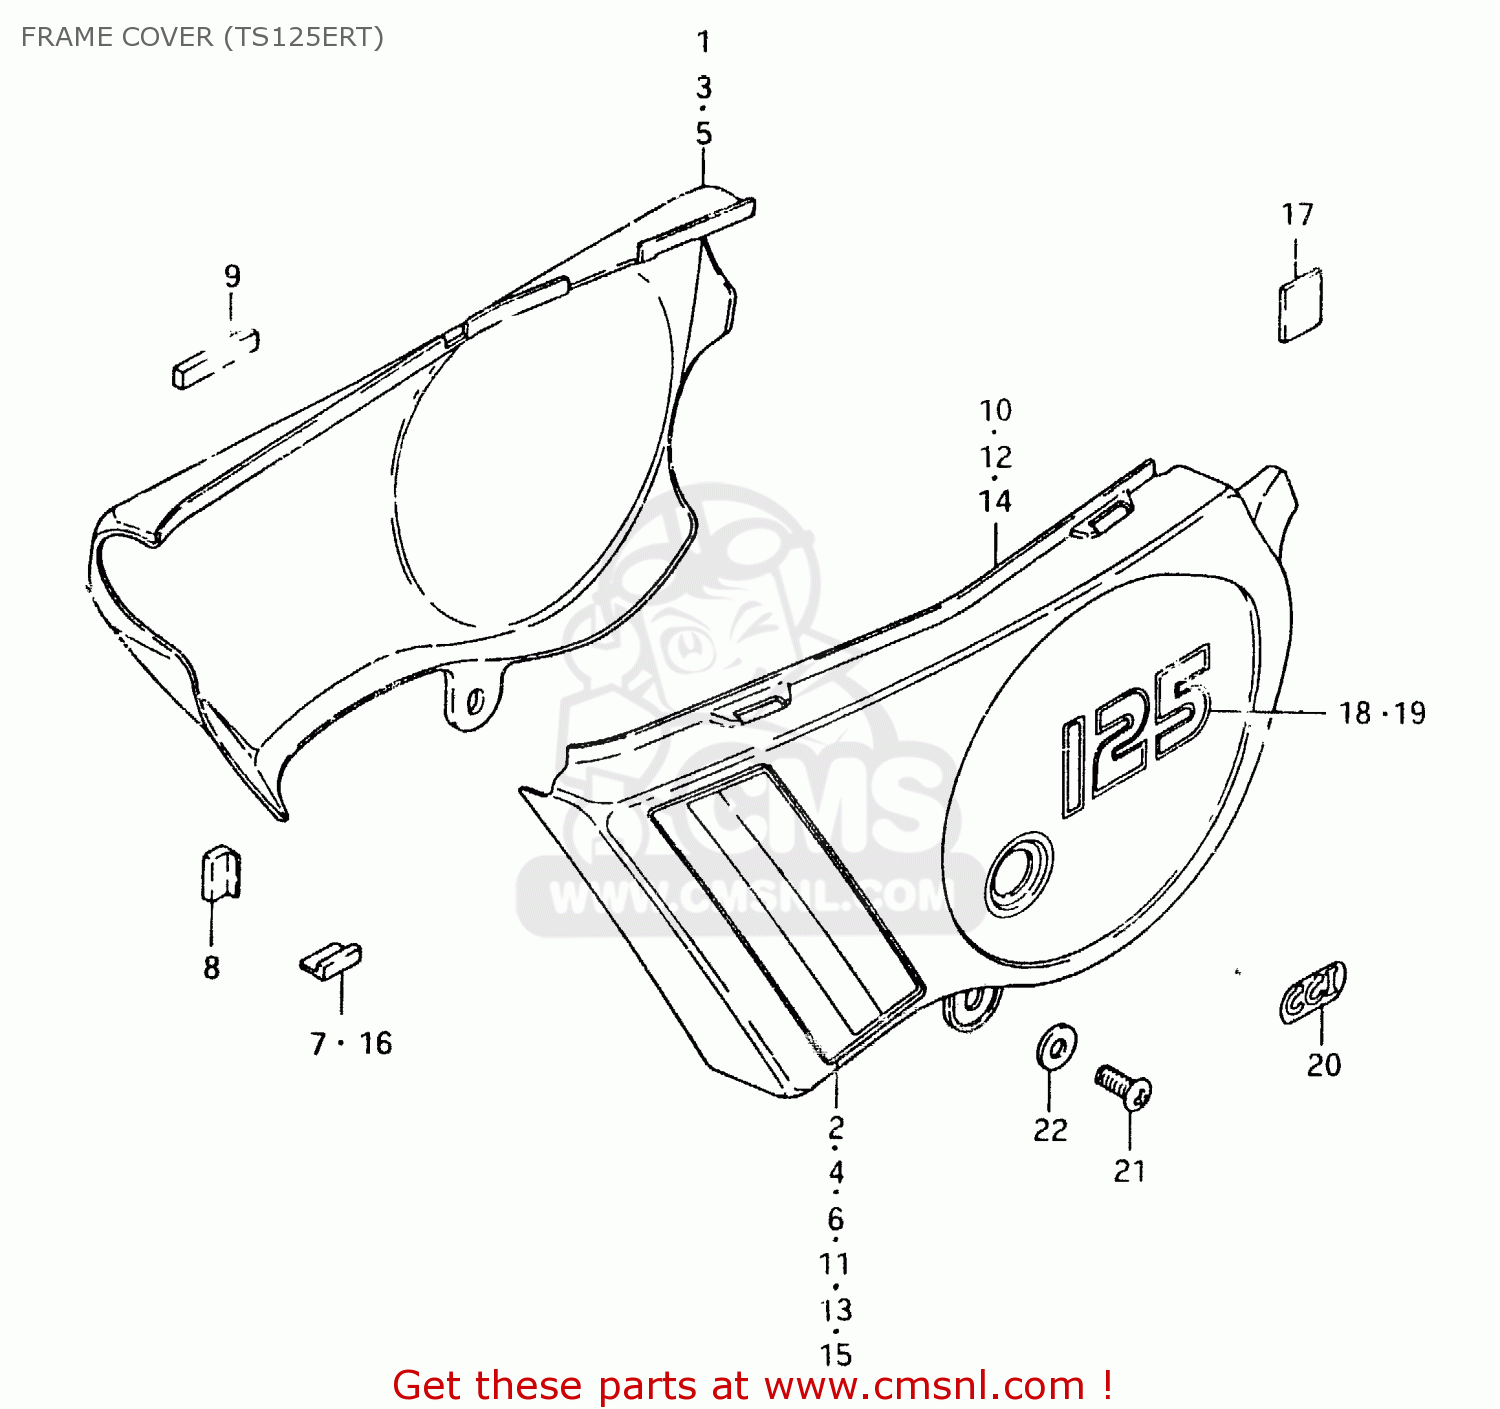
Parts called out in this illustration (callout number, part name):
1	COVER, FRAME RH (RED)
2	TAPE, RH
3	COVER,FRAME,RIGHT
4	TAPE, RH
5	COVER, FRAME RH (WHITE)
6	TAPE, RH
7	CUSHION,FRAME COVER
8	CUSHION,FRAME COVER
9	CUSHION,FRAME COVER
10	COVER, FRAME LH (RED)
11	TAPE, LH
12	COVER,FRAME,LEFT
13	TAPE, LH
14	COVER, FRAME LH (WHITE)
15	TAPE LH
16	CUSHION,FRAME COVER
17	PROTECTOR(170X95X3.0)
18	EMBLEM "125" RH
19	EMBLEM "125" LH
20	EMBLEM,CCIS
21	SCREW 6X12
22	WASHER
